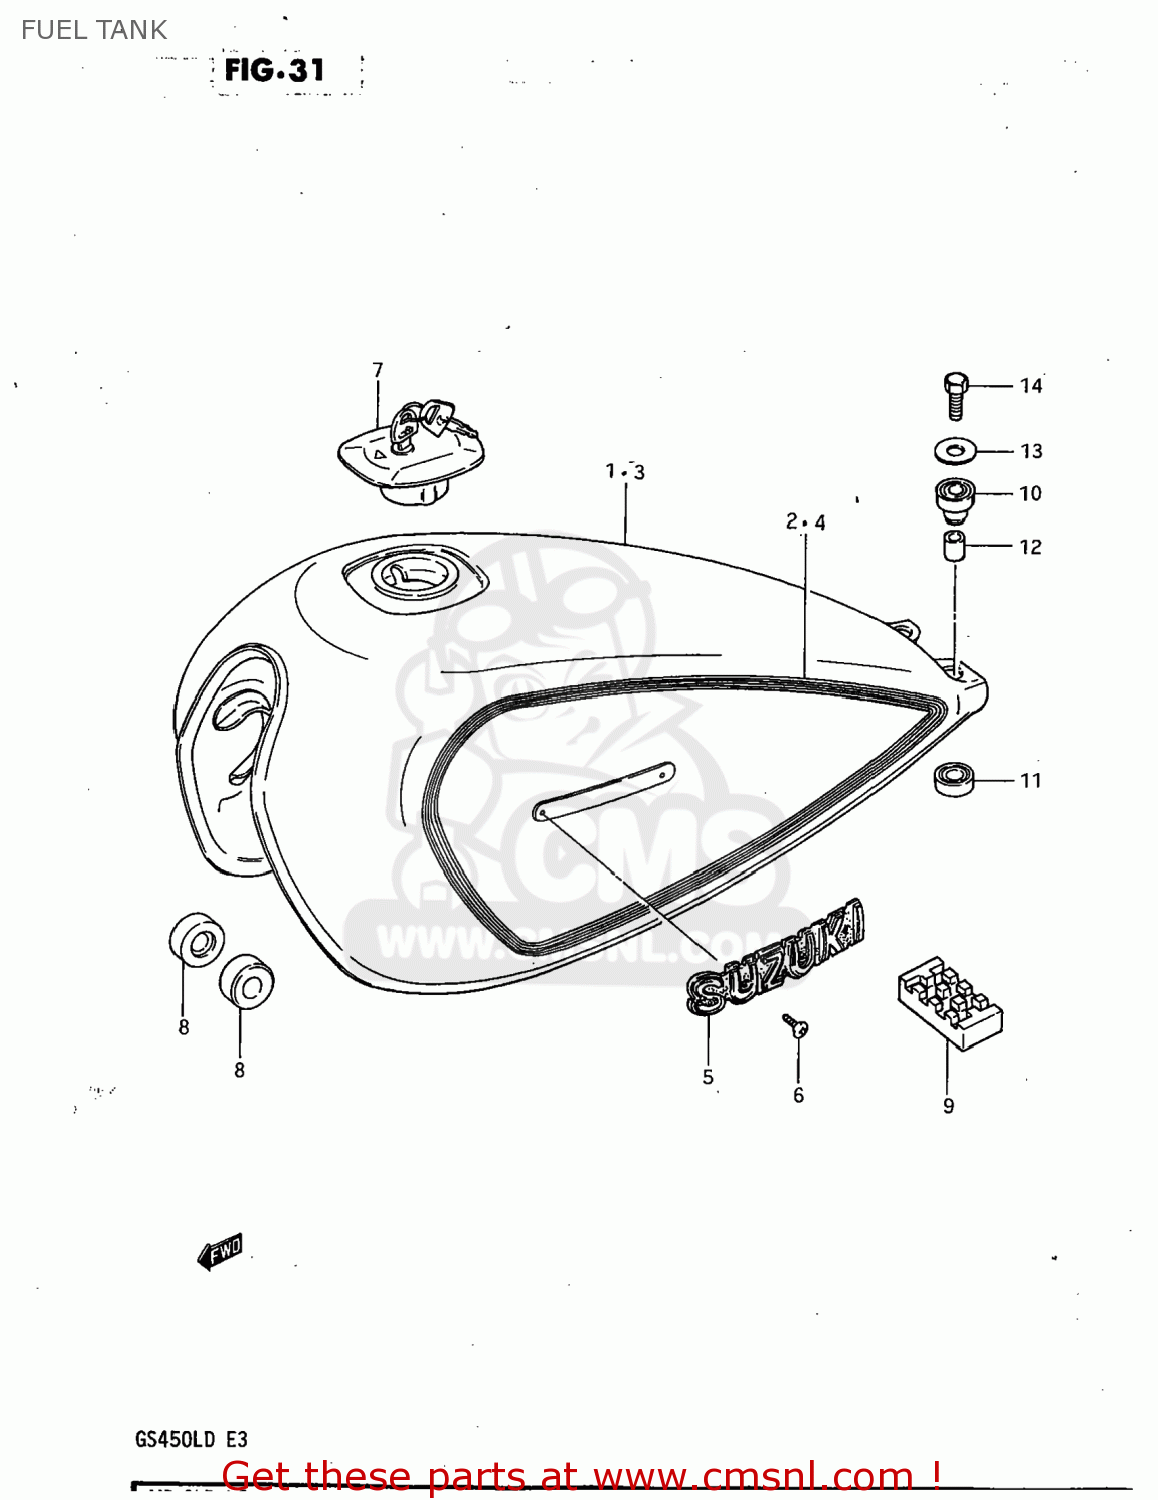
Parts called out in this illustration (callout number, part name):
1	TANK ASSEMBLY,FUEL
2	TAPE SET,FUEL TANK
3	TANK ASSEMBLY,FUEL
4	TAPE SET,FUEL TANK
5	EMBLEM,FUEL TANK
6	SCREW 3X6
7	CAP SET,FUEL TANK
8	CUSHION
9	CUSHION
10	CUSHION
11	CUSHION
12	SPACER (6.4X9X20)
13	WASHER (6.5X24X1.6)
14	BOLT
